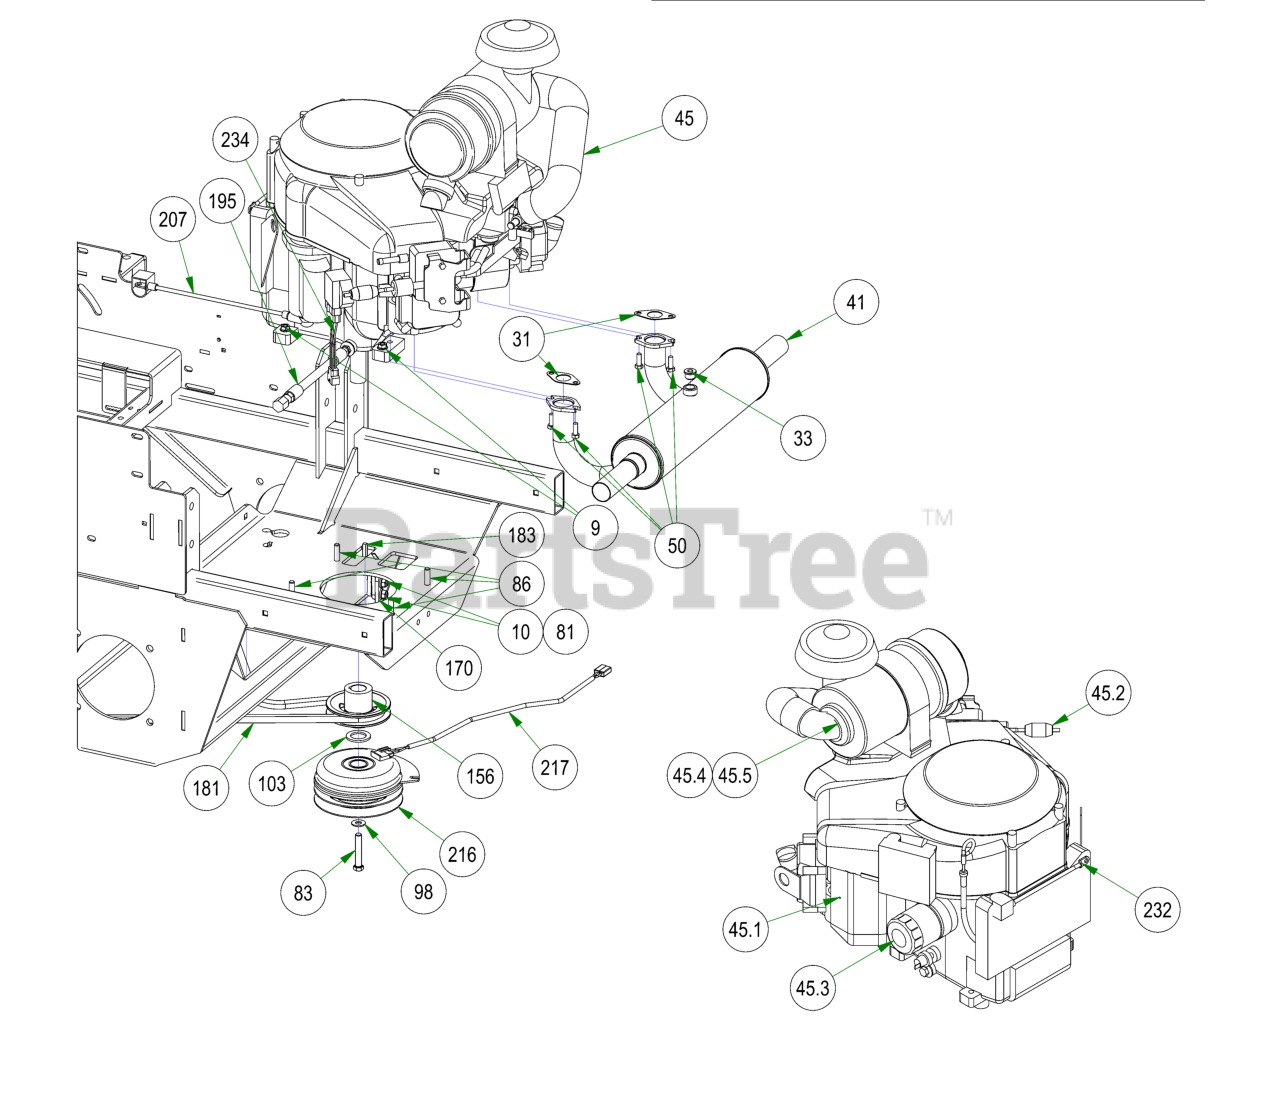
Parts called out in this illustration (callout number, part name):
9	3/8-16 HEX SERRATED FLANGE NUT HARD/ZINC
10	3/8-16 NYLON INSERT FLANGE LOCKNUT (GR.F) ZINC
31	Exhaust Gasket for 23 Vanguard
33	O2 Sensor Plug
41	Muffler for 36Hp Vanguard
45	993cc Vanguard Engine
45.1	Spark Plug
45.2	Universal Inline Fuel Filter
45.3	Oil Filter
45.4	Canister Air Filter- Outer
45.5	Canister Air Filter- Inner
50	Torx Bolt-Exhaust
81	3/8-16 X 1 CARRIAGE BOLT (GR.5) ZINC
83	7/16-20 X 2-1/2 HEX Bolt GR 8 W/ Patch
86	3/8-16 X 1-1/2 HEX CAP SCREW (GR.5) ZINC
98	3/8 FLAT WASHER USS (1" OD) ZINC
103	1.140 ID X 1.750 OD X .132 THICK FLAT WASHER PLAIN
156	4 3/4 Motor Pulley
170	Rebel Clutch Tab
181	2019 Rebel Pump Belt
183	1/4 X 1 SQ MACHINERY KEY 1018 STL PLN
195	14 mm Oil drain Hose 993cc Vanguard
207	14" Red Battery Cable-Base Outlaw
216	Clutch Assembly
217	Clutch Pigtail
218	2022 Rebel Frame
232	Starter Cable
234	2019 Harness Adaptor - 36 Vanguard Carberated
